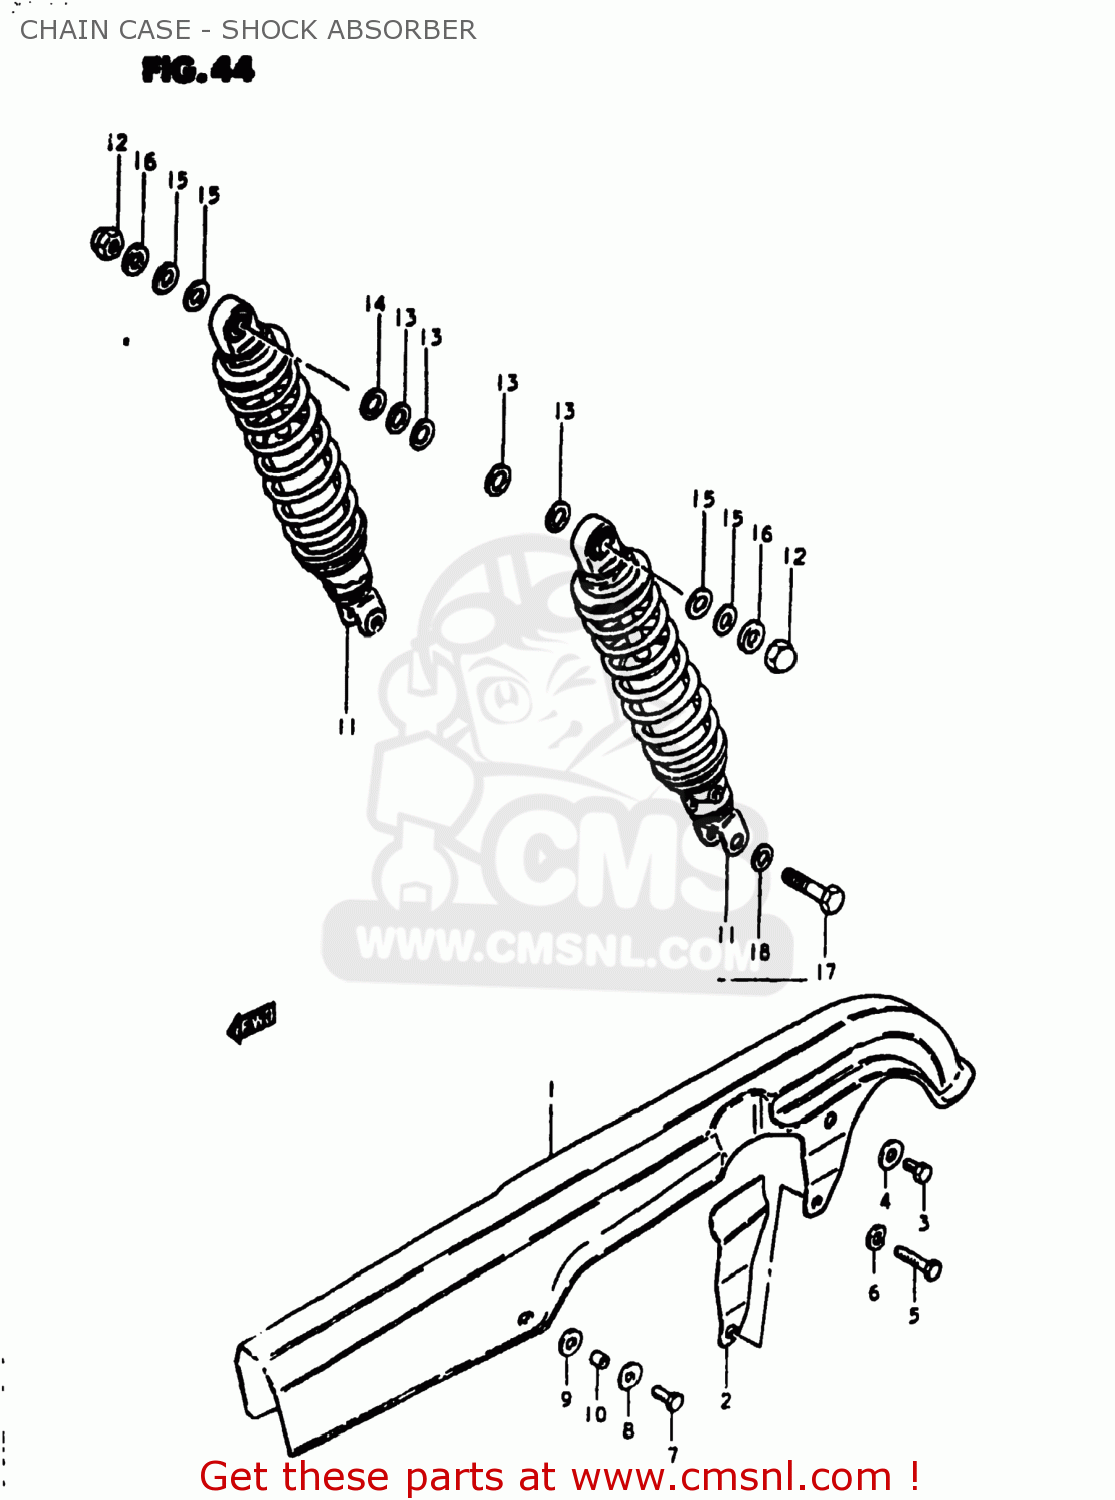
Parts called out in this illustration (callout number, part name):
1	CASE,CHAIN
2	REINFORCEMENT,CHAIN CASE
3	BOLT(6X8)
4	WASHER
5	BOLT
6	LOCK WASHER
7	BOLT
8	WASHER(6.5X18X1)
9	CUSHION
10	SPACER (6.1X8X5.2)
11	ABSORBER ASSEMBLY,REAR SHOCK
12	NUT, LOWER LH
13	WASHER
14	WASHER (12.5X24X3.2)
15	WASHER
16	WASHER(10.5X24X3.2)
17	BOLT(10X36)
18	WASHER
